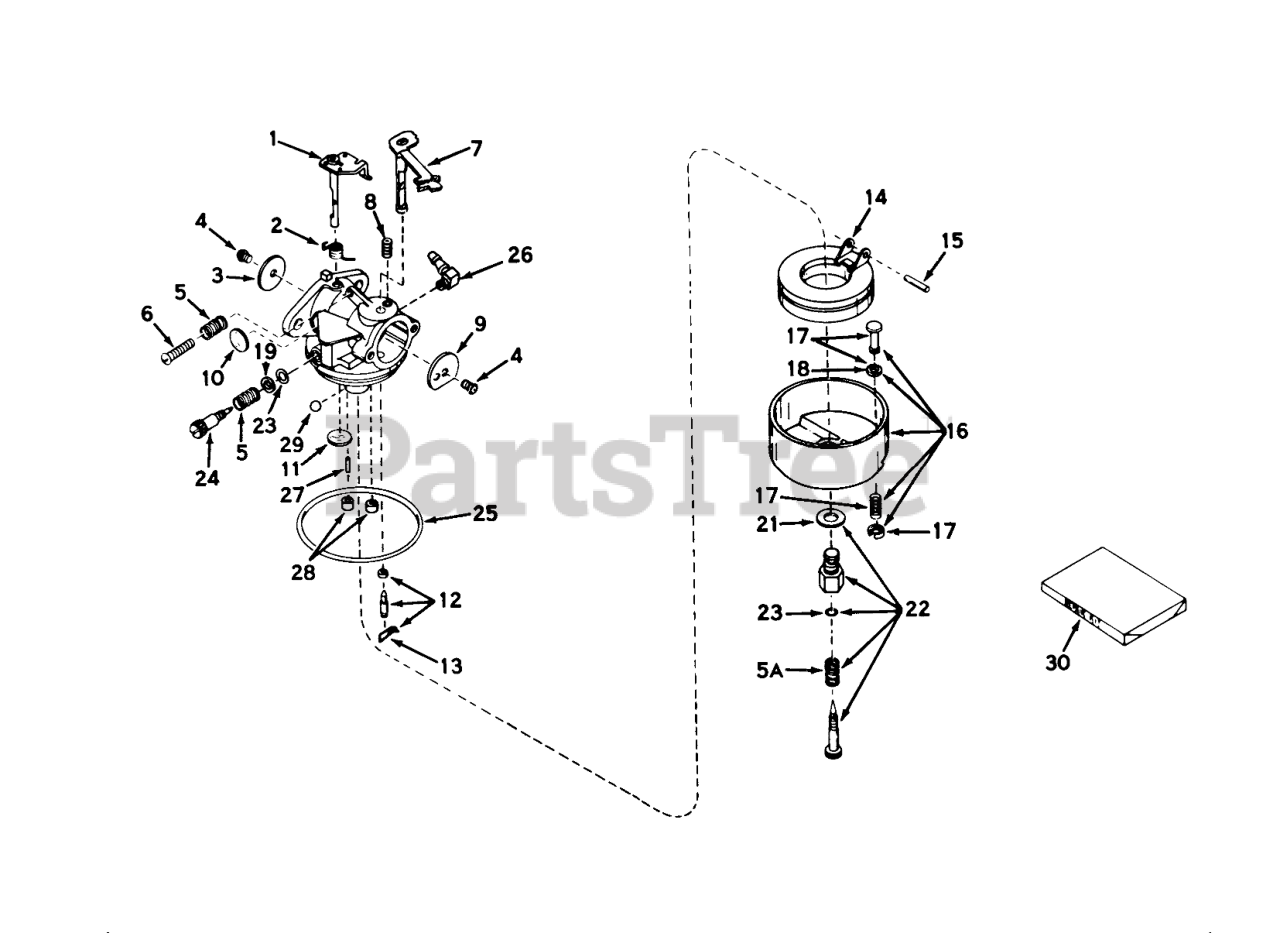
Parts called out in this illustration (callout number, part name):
1	Shaft & Lever Assy.
2	Spring, Throtte Return
3	Shutter-Throttle
4	Screw-Shutter
5	Spring-Tension
6	Screw-Throttle Crack Screw / Idle Speed
7	Shaft & Lever Assy., Choke
8	Spring-Positioning, Choke
9	Shutter-Choke
10	Plug-Welch, Idle Mixture Well
11	Plug-Welch, Atmospheric Vent
12	Inlet Needle, Seat & Clip Assy.(Incl. No. 13)
13	Clip-Spring
14	Float,Carburetor
15	Shaft-Float
16	Bowl & Drain Assy., Float (Incl. No. 17)
17	Plunger Assy., Drain (Incl.No. 18)
18	Gasket-Plunger, Drain
21	Washer-Bowl Nut
22	Adjustment Screw Assy., Main (Incl. Nos. 5A, 21 & 23)
23	"O"Ring
24	Screw, Idle Adj.
25	O Ring-Bowl, Float
26	Fitting Fuel Inlet
28	Plug, Cup
29	BalI, Steel
30	Kit-Repair
